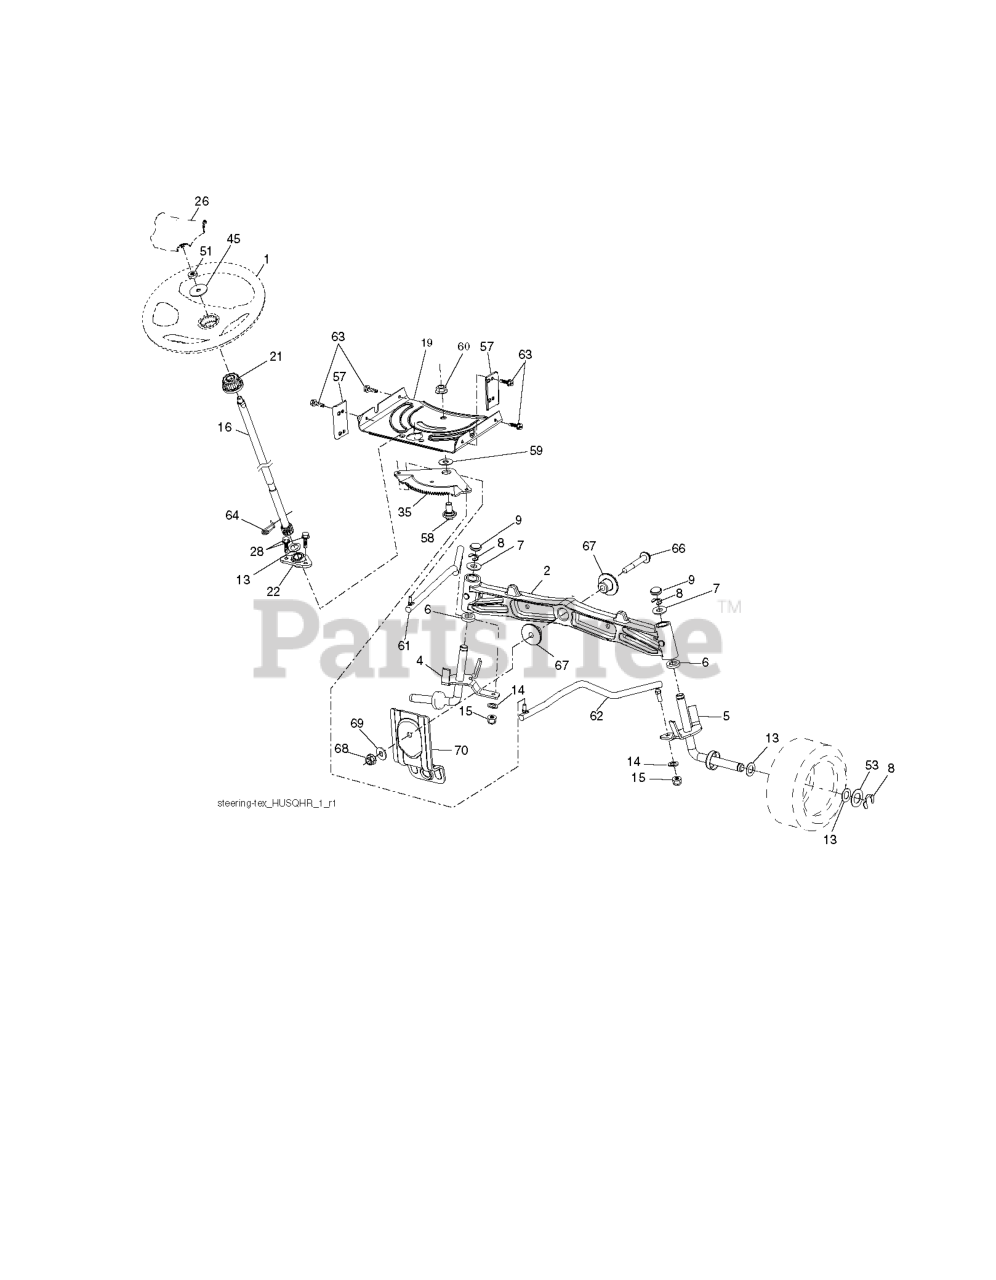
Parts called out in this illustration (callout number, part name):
1	RP WHEEL.STEER.HUSQ.PREM.OVMLD
2	AXLE.CAST.IRON
4	SPINDLE.WELDED.LH.15"TEX
5	SPINDLE.WELDED.RH.15"T
6	THRUST WASHER
9	CAP.SPINDLE.BLACK
14	WASHER, LOCK 3/8
15	NUT CROWNLOCK 3/8-24
16	SHAFT, STEERING
19	PLATE.STEER.DDL.NLT/NG
21	ADAPTER, WHEEL STNG..
22	STEERING.SUPT.LOWER.
26	RP INSERT.CAP.WHL.STRG.HUSQ.
28	SCREW, 3/8-16X3/4
35	GEAR.SECTOR.PLATE.DDL.
45	WASHER 9/16"ID, 2 3/8"OD
51	NUT.HEX.1/2-20
53	WASHER.HARDENED
57	BRACKET.UPSTOP.TEX
58	BOLT.SHOULDER.SECTOR.P
59	WASHER.THURST.SECTOR.S
60	NUT FLANGE LOCK 5/8-11
61	DRAGLINK.LH.BALLSTUD.D
62	DRAGLINK.RH.BALLSTUD.D
63	SCREW
64	RETAINER.CLIP.SPRING.S
66	BOLT HEX FGHD 7/16-14 X 3 SERR
67	BUSHING.PM.FRONT AXLE
68	NUT.LOCK.FLANGE.7/16
69	WASHER.1.5X.505X.118
70	BRKT.DECK.SUSPENSION.F
